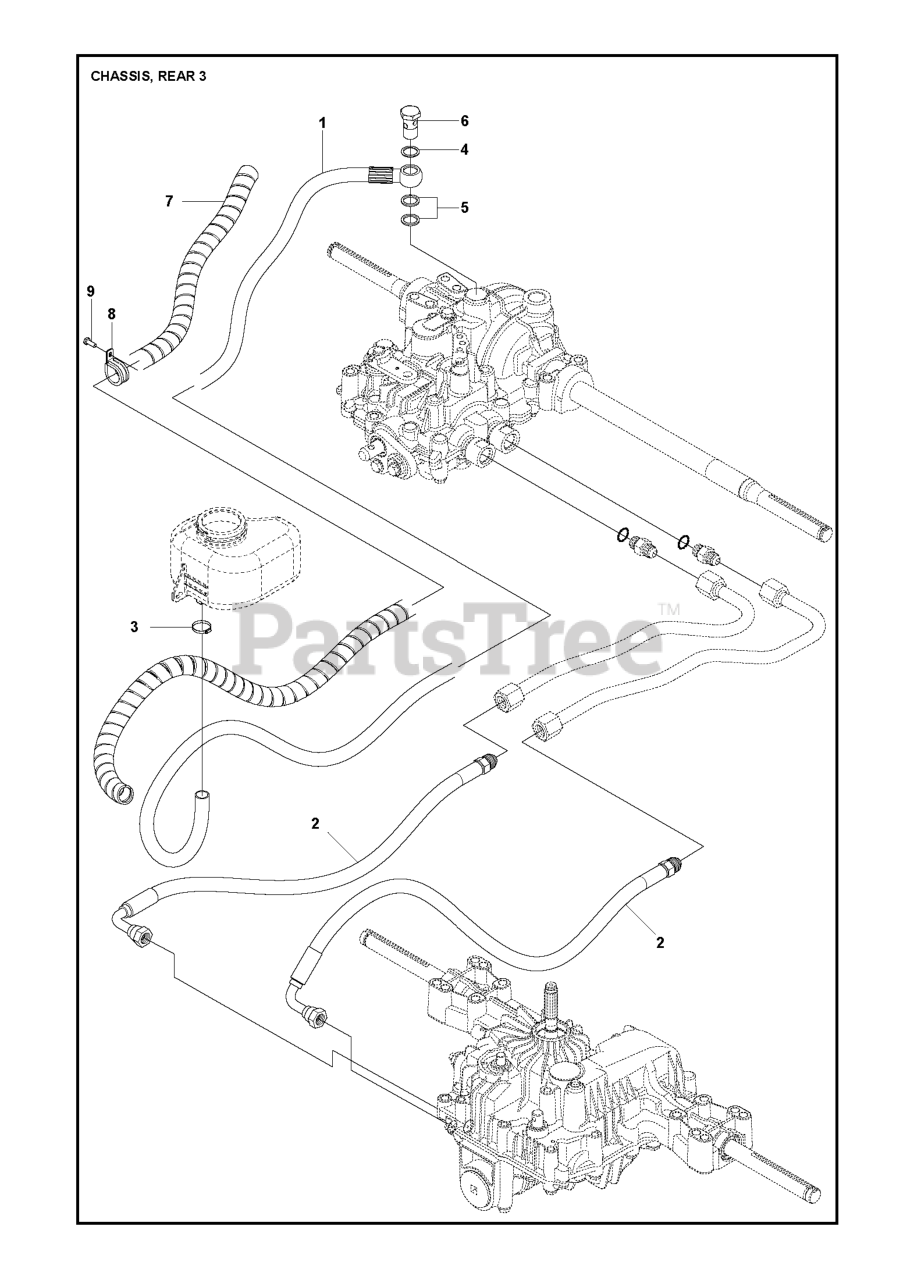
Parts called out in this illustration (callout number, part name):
1	HYDRAULIC HOSE
2	HYDRAULIC HOSE
3	HOSE CLAMP 20-32
6	PIPE FITTING
7	HOSE GUARD
8	HOSE CLAMP
9	SCREW
